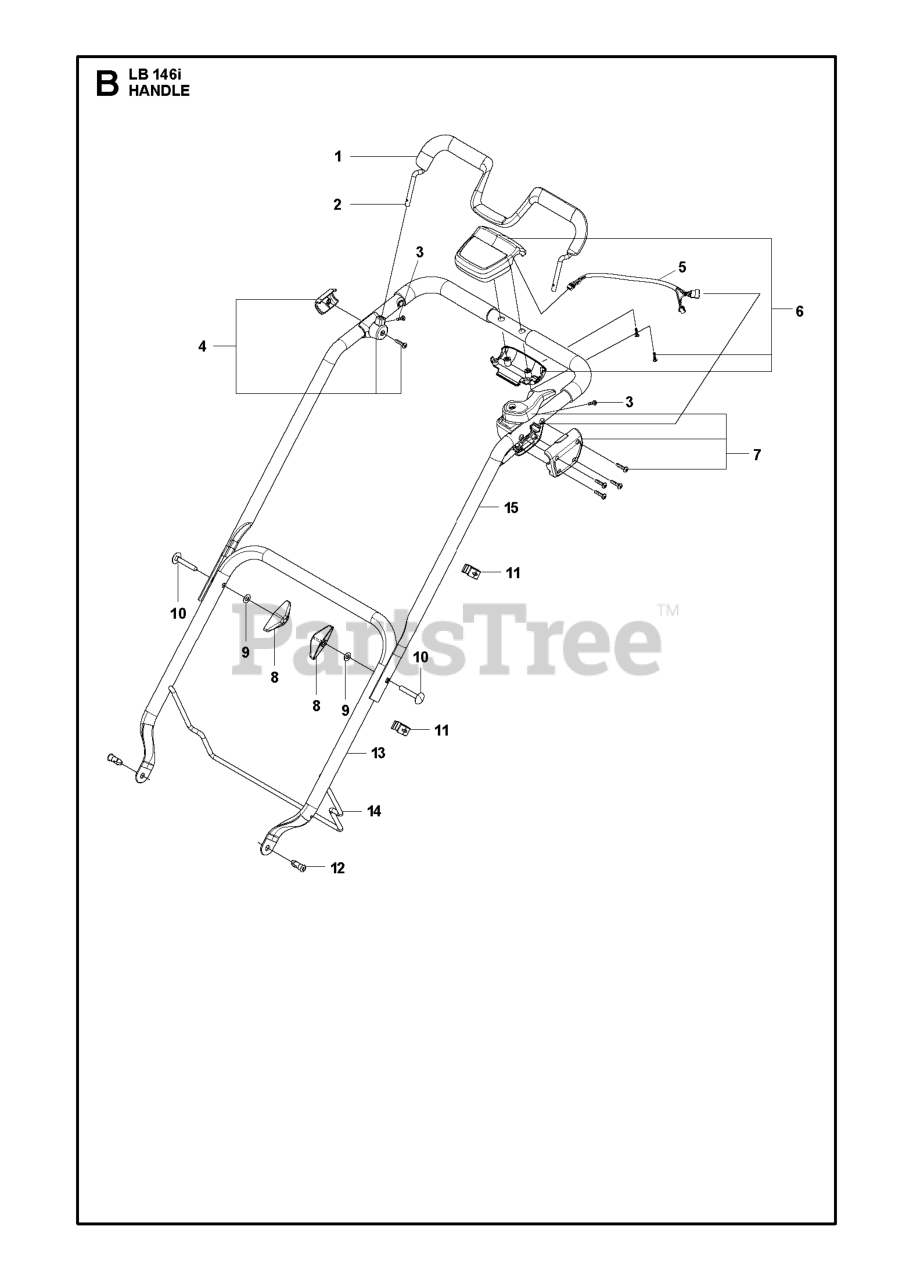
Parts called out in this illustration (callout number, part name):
1	GRIP HANDLE ASSY OPC BAIL
2	BAIL HANDLE ASSY OPC BAIL
3	DRIVE SCREW HANDLE ASSY M4 BAI
4	BAIL ARM ASSY SPARE PART ASSY
5	EXTENSION CABLE CONTROL PANEL
6	CONTROL BOARD ASSY LE121P
7	SWITCHBOX ASSY ASSY LC247LI
8	WINGNUT
